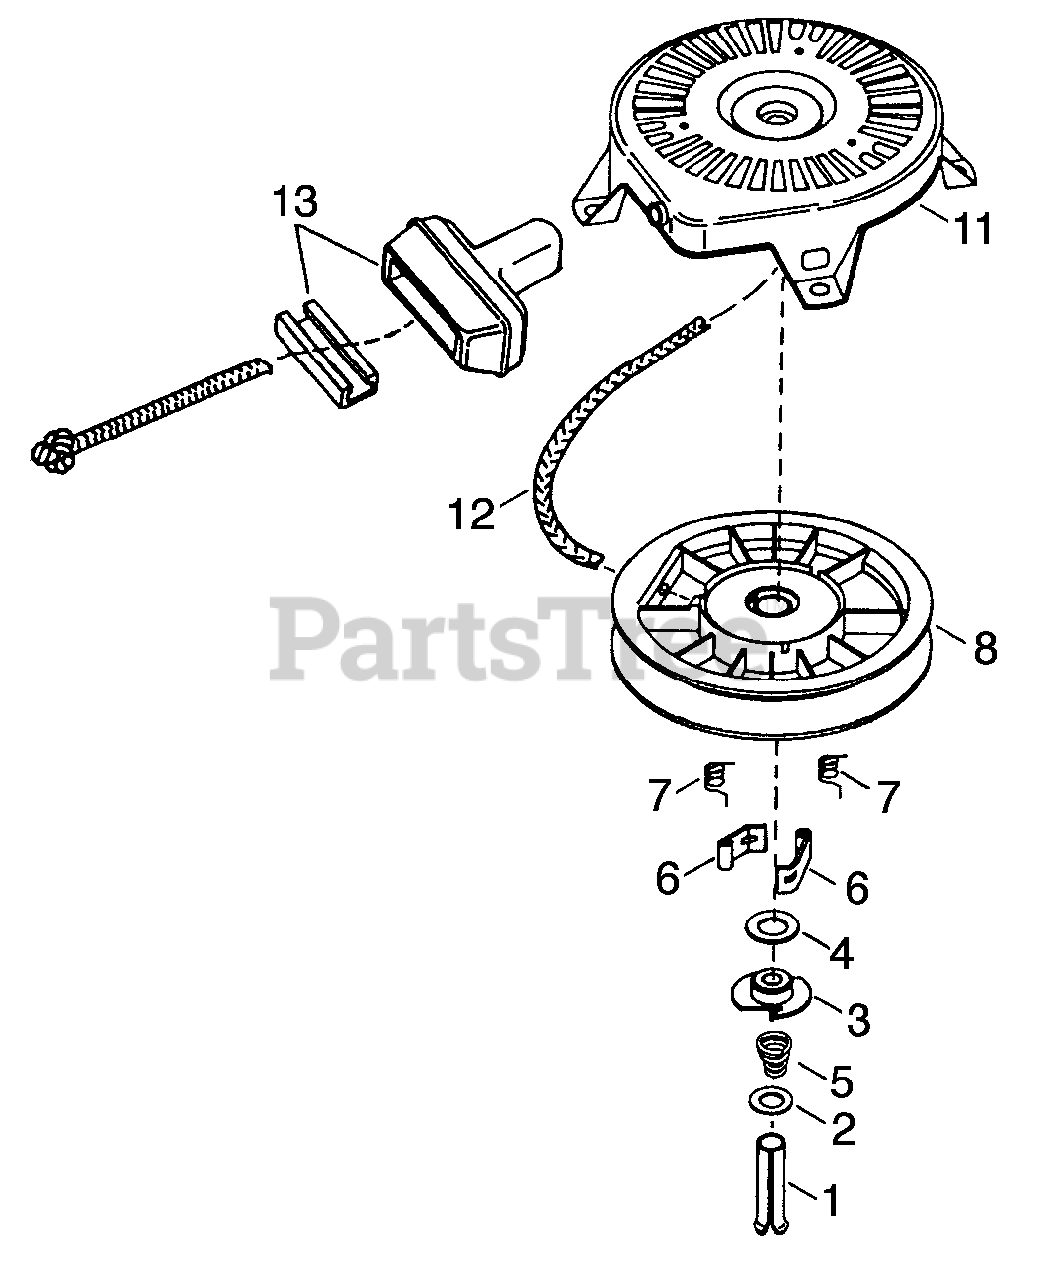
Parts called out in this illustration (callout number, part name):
5	Brake Spring
6	Starter Dog
7	Dog Spring
8	Pulley & Rewind Spring Assy
11	Starter Housing Assy
12	Starter Rope
13	Starter Handle
